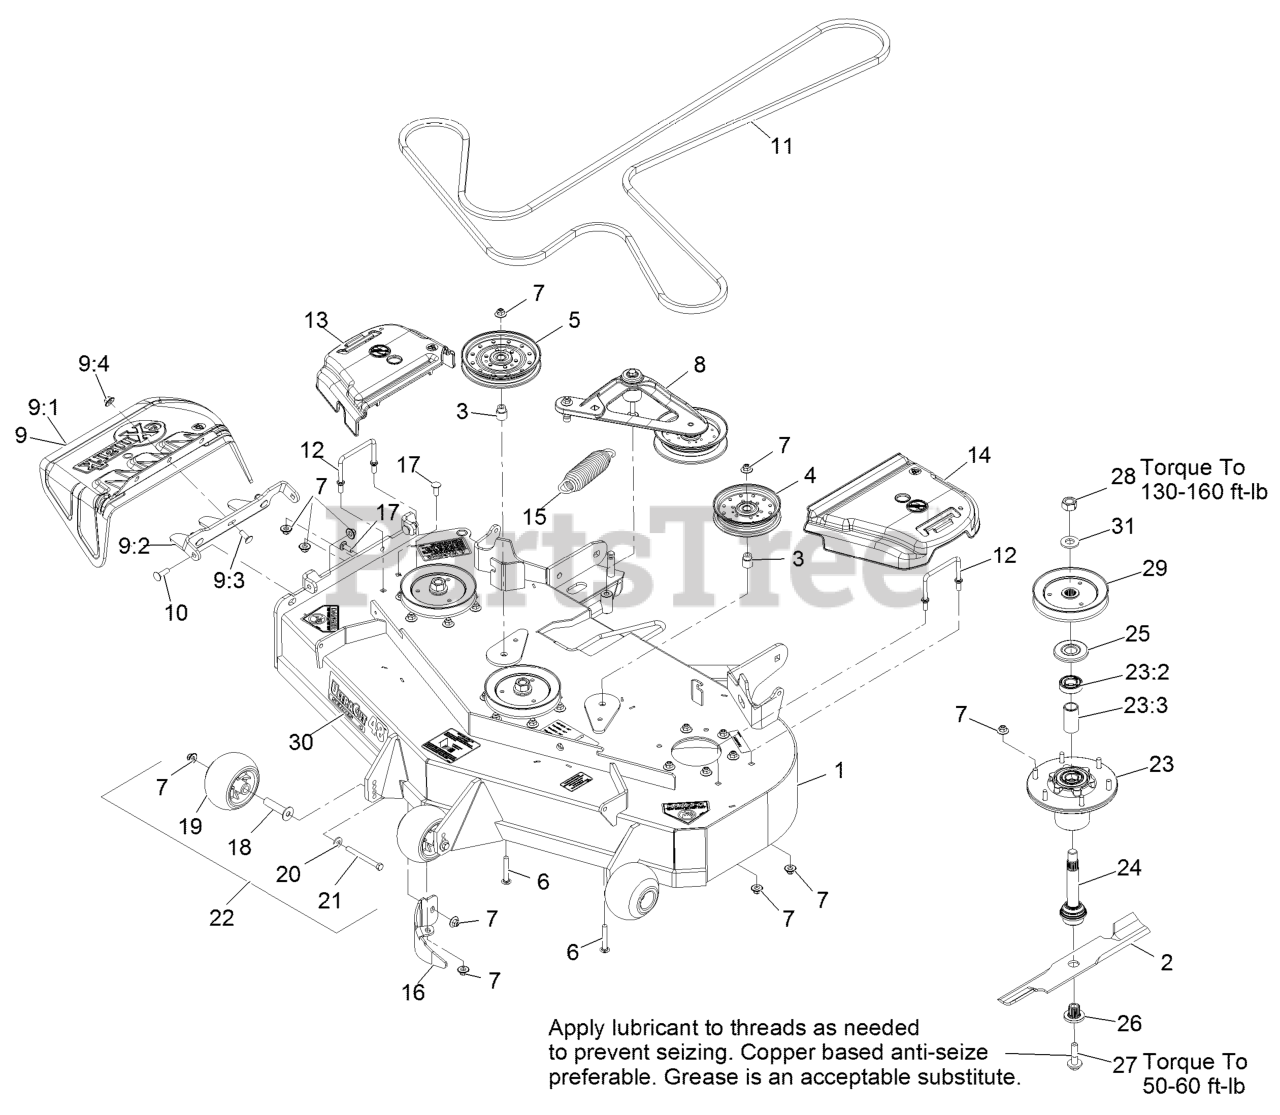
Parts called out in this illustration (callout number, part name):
1	ASM,DECK W/DECALS 48
3	BUSHING-IDLER
6	SCREW-CARR
7	Nut-Nyloc 3/8-16 Flg
8	DECK IDLER ASM
9	ASM,DISCHARGE CHUTE
9:1	CHUTE,DISCHARGE
9:2	BRACKET,DISCHARGE CHUTE
9:3	SCREW-CARR
9:4	Nut-Nyloc 3/8-16 Flg
10	Bolt-Carriage 3/8-16 X 1 1/4
11	BELT
12	WIREFORM-COVER
13	COVER-BELT, RH
14	COVER-BELT, LH
15	SPRING-EXTENSION
16	BAFFLE-DOGLEG,LZS LZX VT4
17	SCREW-CARR
18	AXLE, ROLLER
19	ROLLER-SCALP, ANTI
20	WASHER-BELLEVILLE
21	SCREW-HH 3/8-16 X 3 3/4 GR 8
22	KIT, ANTI-SCALP ROLLER
23	ASM-CUTTER HSG WITH BEARINGS
23:2	BEARING-BALL
23:3	SPACER-BEARING
24	ASM-SPINDLE AND SEAL
25	GUARD,BEARING TOP .989
26	BUSHING,SPLINED
27	SCREW,SEMS 1/2-20 X 2.19
28	NUT-HEX
29	SHEAVE,BLADE DRIVE 5.90
30	DECAL,ULTRACUT 48 SERIES
